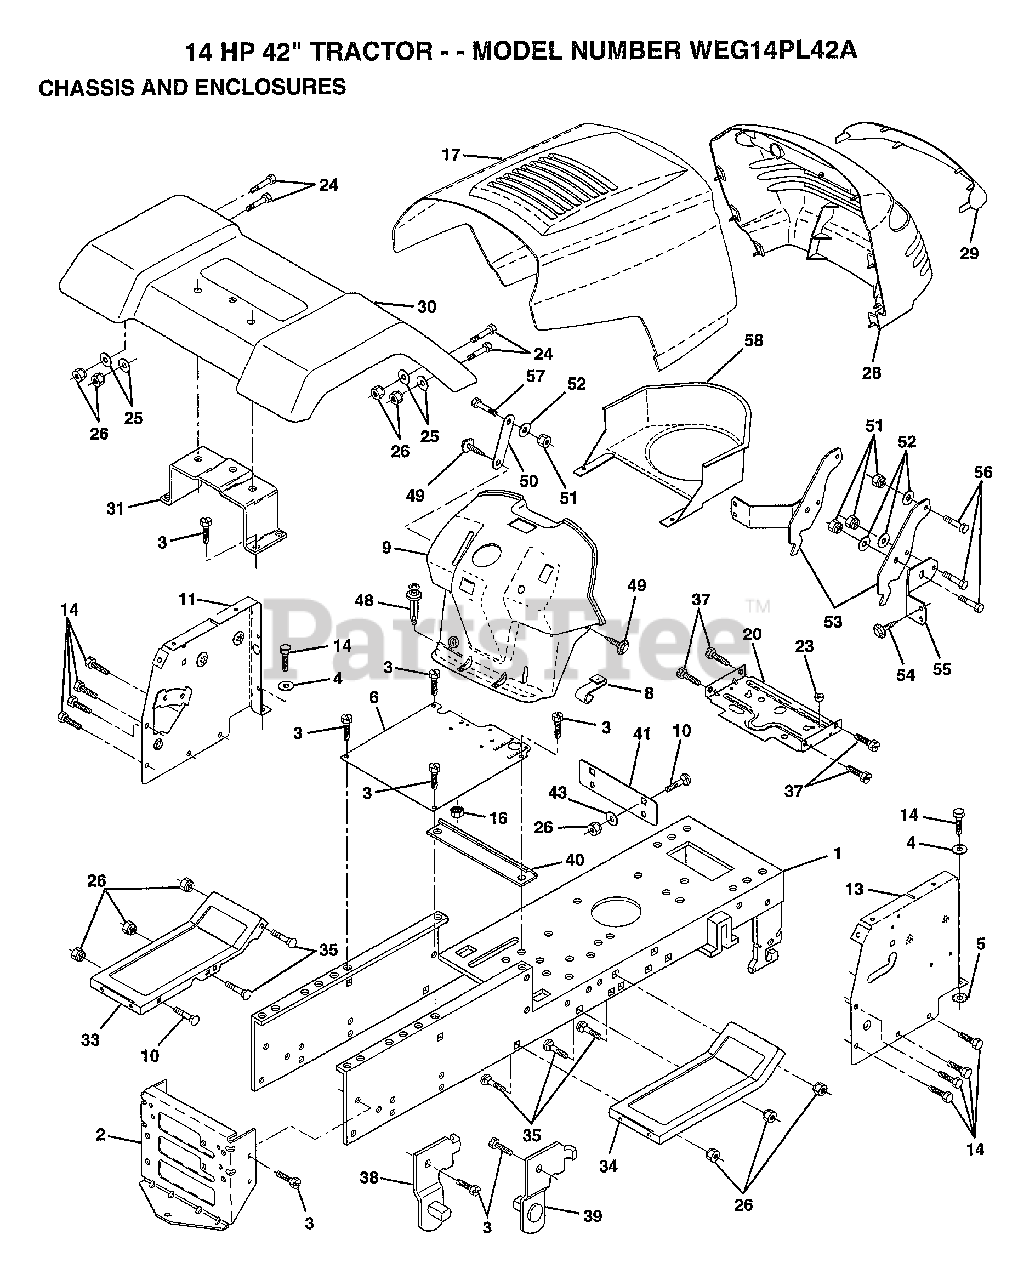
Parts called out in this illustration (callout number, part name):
3	SCREW
4	WASHER
5	LOCKWASHER
8	"CLIP,INSULATOR"
14	SCREW LT
16	NUT
24	BOLT
25	WASHER
26	NUT
29	LENS GRILLE
31	BRACKET SUPT FEND
35	BOLT
37	SCREW
38	BRACKET ASM LH
39	BRACKET ASM RH
40	SPACER FENDER LT
41	PLATE EXTEN FEND
43	WASHER
48	RIVET.PUSH.PLATE
49	SCREW HEX CRT
50	BRACE SUPT DASH
51	NUT
52	WASHER
53	HING PICK-OFF HD
55	BRACKET GRILLE
56	BOLT LT
58	DUCT AIR 12-15H
